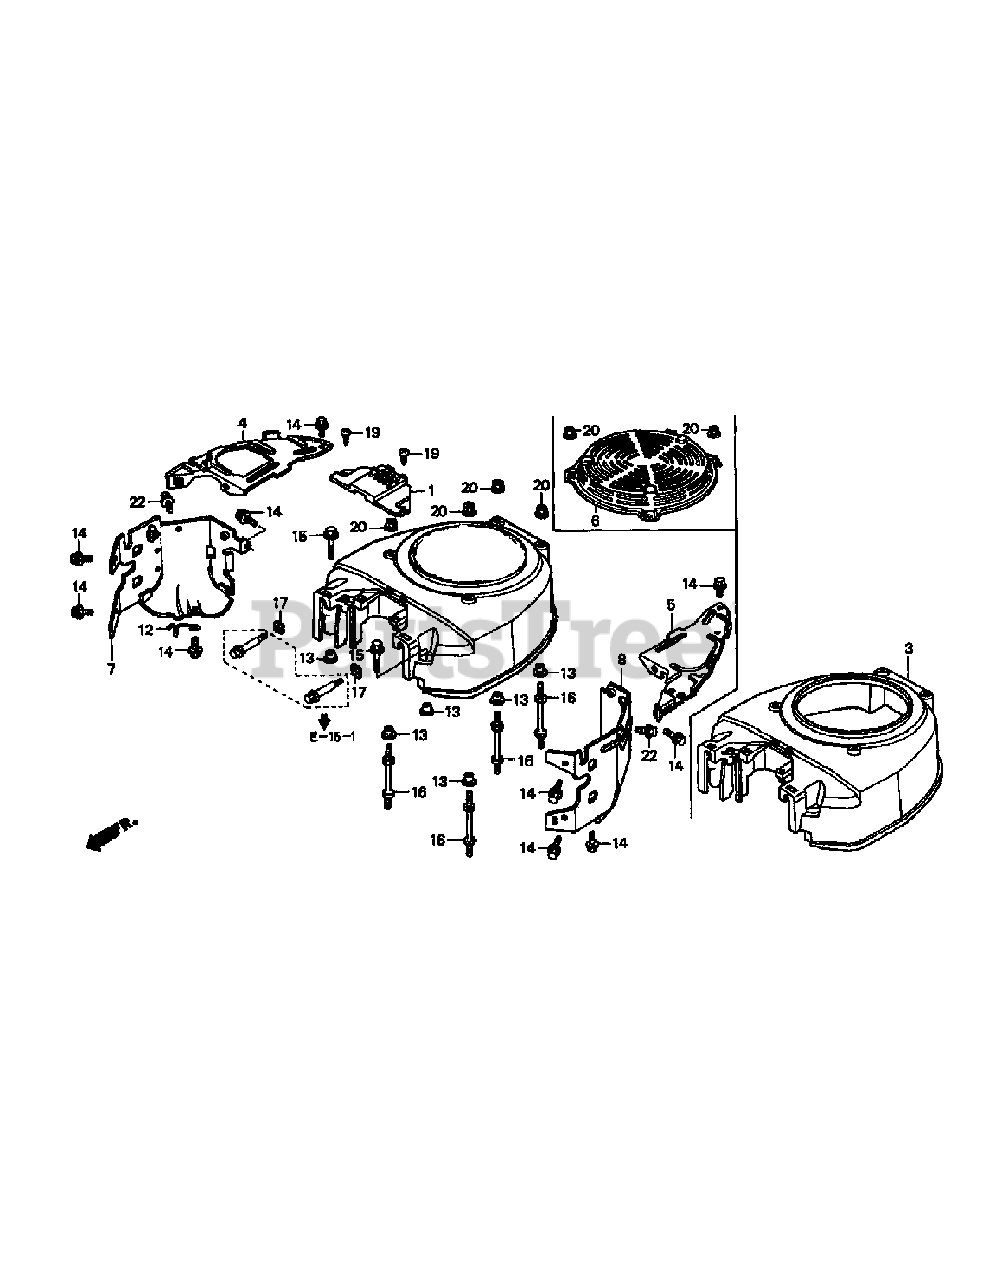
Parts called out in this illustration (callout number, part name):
1	Fuel Pump Cover
3	Fan Cover (Black)
4	Side Plate R.H.
5	Side Plate L.H.
6	Fan Cover Protector (Black)
7	Shroud R.H.
8	Shroud L.H.
12	Ignition Tube Clamp
14	Flange Bolt (6x12)
15	Flange Bolt (6x23)
16	Stud Bolt (6x71)
17	Square Nut (5mm)
19	Tapping Screw (5x20)
20	Flange Nut (6mm)
22	Flange Bolt (6x8)
